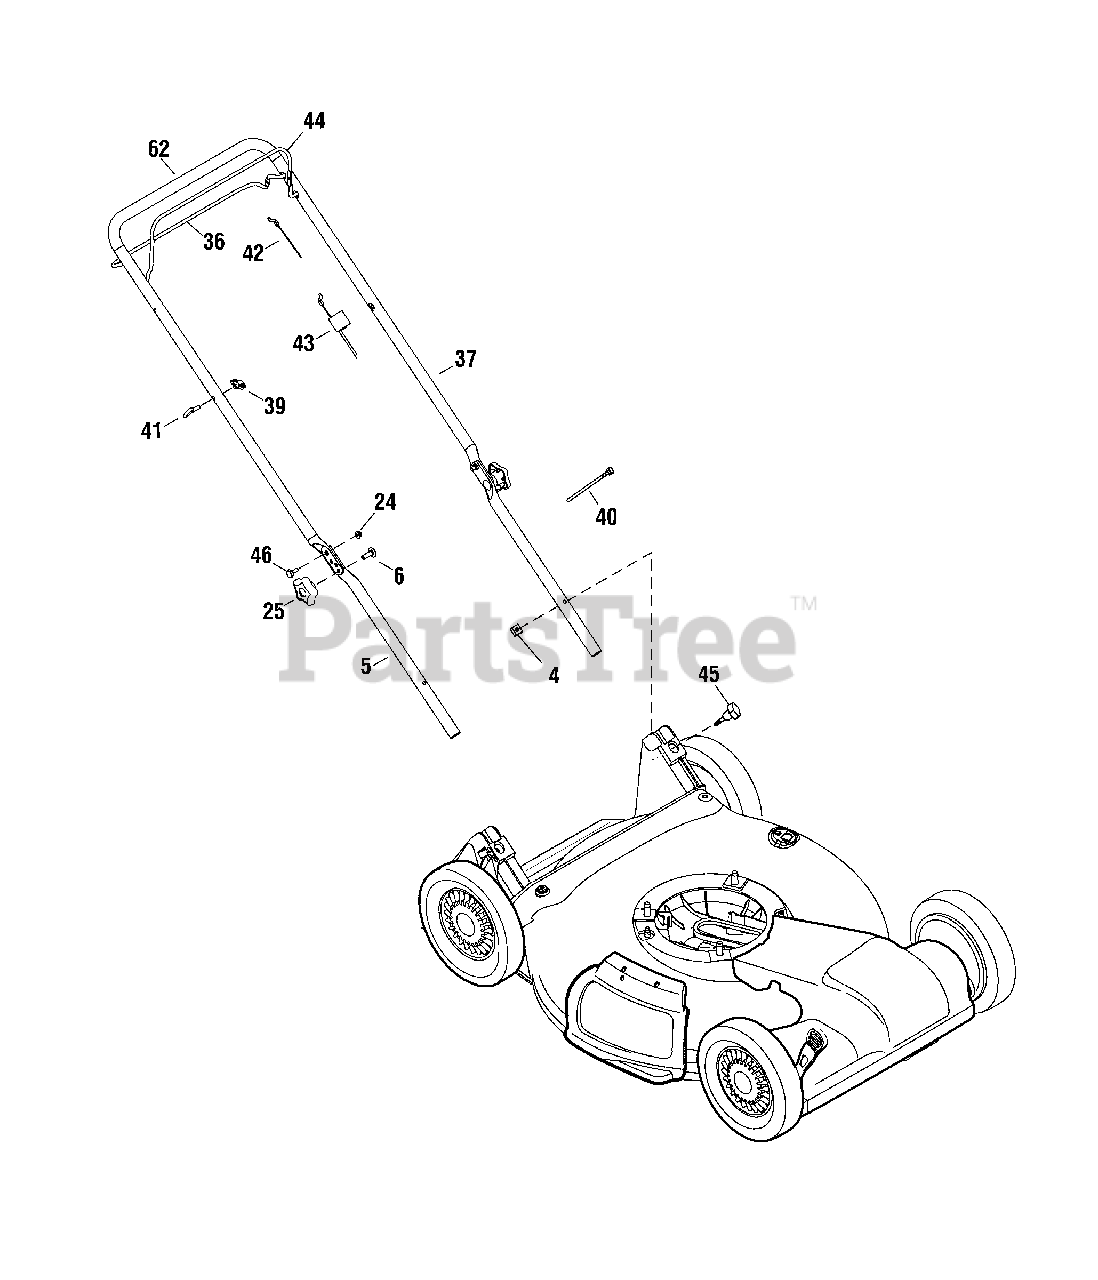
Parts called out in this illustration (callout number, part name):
4	NUT, Square, 1/4-20
5	HANDLE, Lower
6	BOLT, Carriage, 5/16-18 x 1, GR5
24	NUT, Nylock Flanged, 1/4-20
25	KNOB, Wing, 5/16-18
36	BAIL, Drive Control
37	HANDLE, Upper, Adjustable
39	KNOB, 1/4-20
40	TIE, Self Lock
41	GUIDE, Rope
42	CABLE, Control
43	CABLE, Drive
44	BAIL, Blade Control
45	NUT, Wing
46	BOLT, Shoulder, 1/4-20
62	GRIP, Foam
